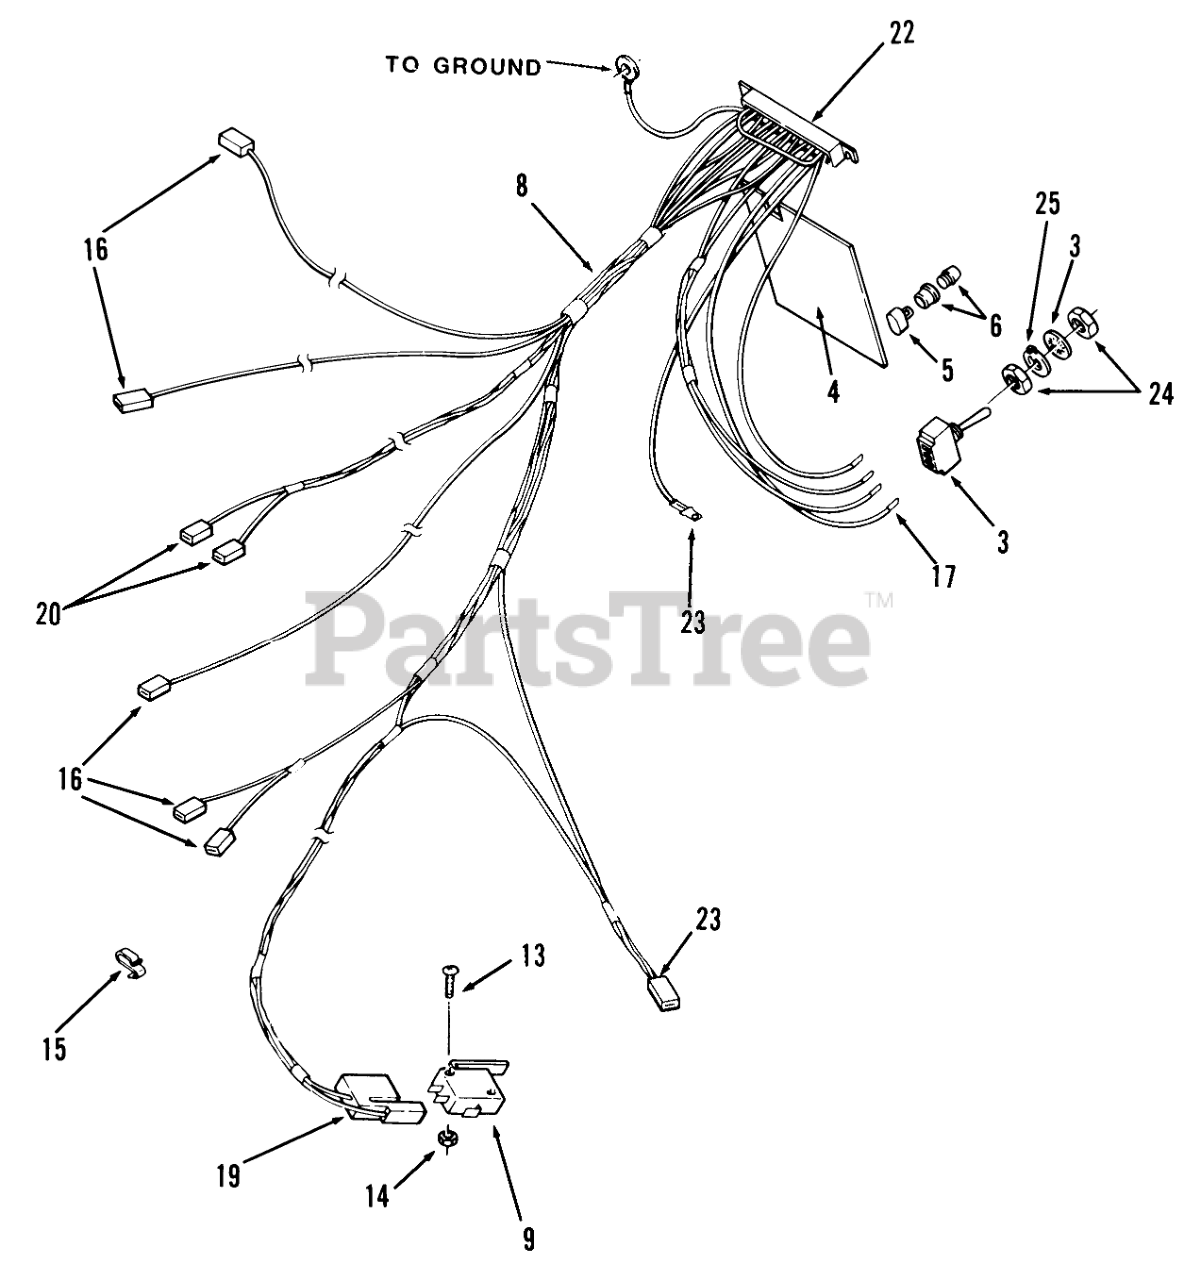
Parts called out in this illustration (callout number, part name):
3	SWITCH TOGGLE
4	P.C. Board (includes item 2)
5	LIGHT INDICATOR
6	ASSY LENS & BUSHING
8	Wiring Harness 211-5 Only
9	SWITCH
13	Screw
14	NUT HEX 4-40 ELAST
15	CLIP-CABLE
16	Piggy-Back Connector (Part of 6)
17	062 X 031 TAB RECEPT
19	CONNECTOR BODY
20	Piggy-Back Connector(Part of 6)
22	Molex Connector (Part of 6)
23	Connector Part of 5
24	NUT F/W 116796
25	RING LOCKING
